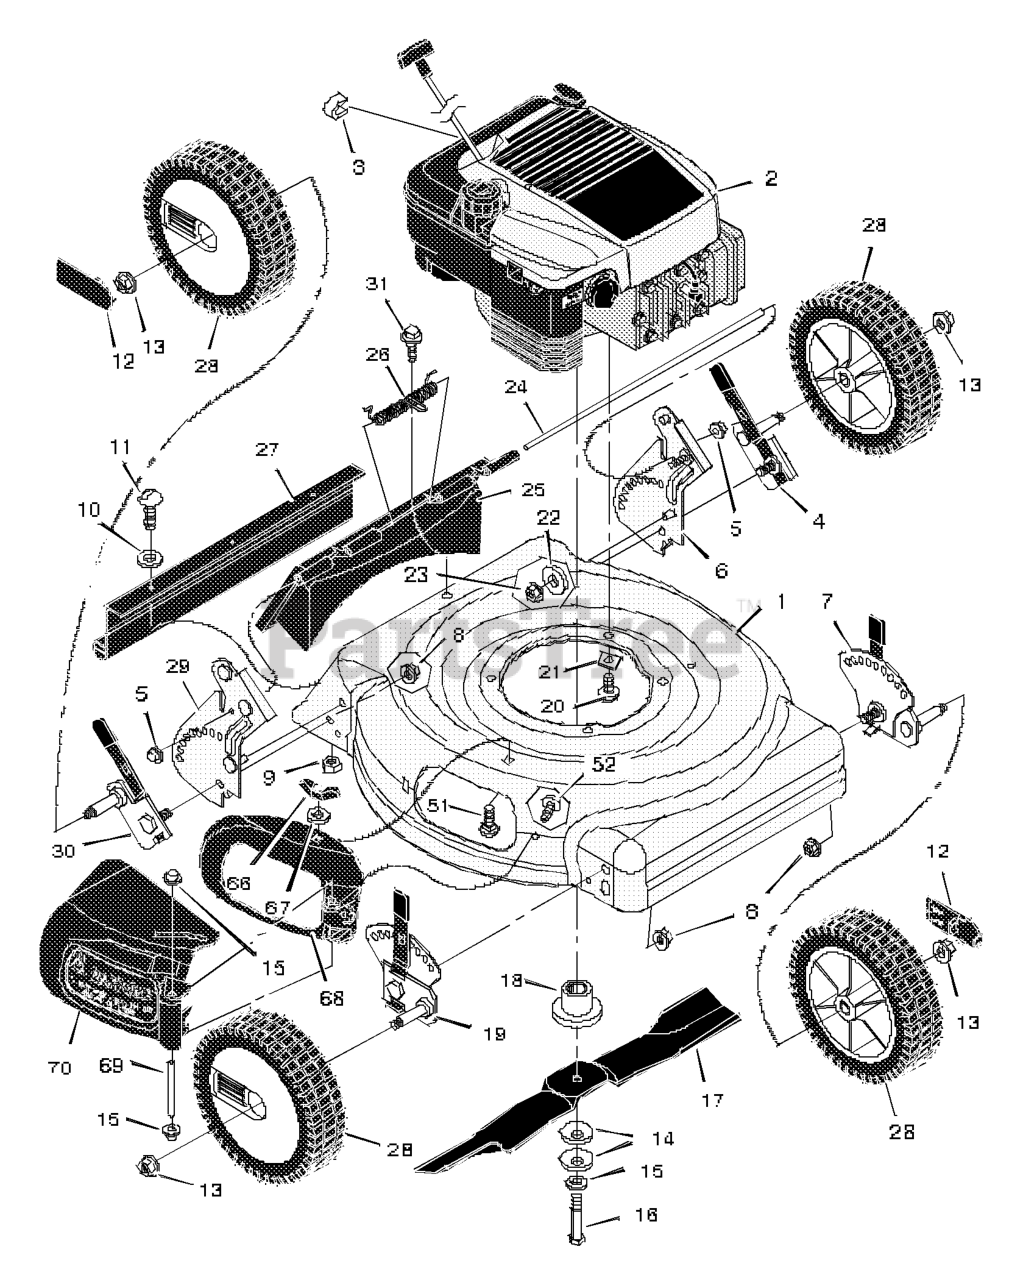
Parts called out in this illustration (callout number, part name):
1	Housing
2	Engine
3	Stop, Rope (Recoil - Start)
4	Adjuster, Left Height
5	Push On Cap
6	Bracket, Left Handle
7	Adjuster, Left Front Height
8	Nut, Flange
9	Nut, Hex
13	Nut, Flange
14	Washer, Belleville
18	Adapter, Blade
19	Adjuster, Right Front Height
20	Bolt, Engine
21	Support, Engine
22	Washer
23	Nut, Flange
24	Rod, Pivot
25	Door, Rear
27	Guard, Rear
28	Wheel
29	Bracket, Right Handle
30	Adjuster, Right Height
51	Bolt, Carriage
66	Wingnut
67	Retainer, Push
69	Pin, Pivot
70	Deflector, Chute
